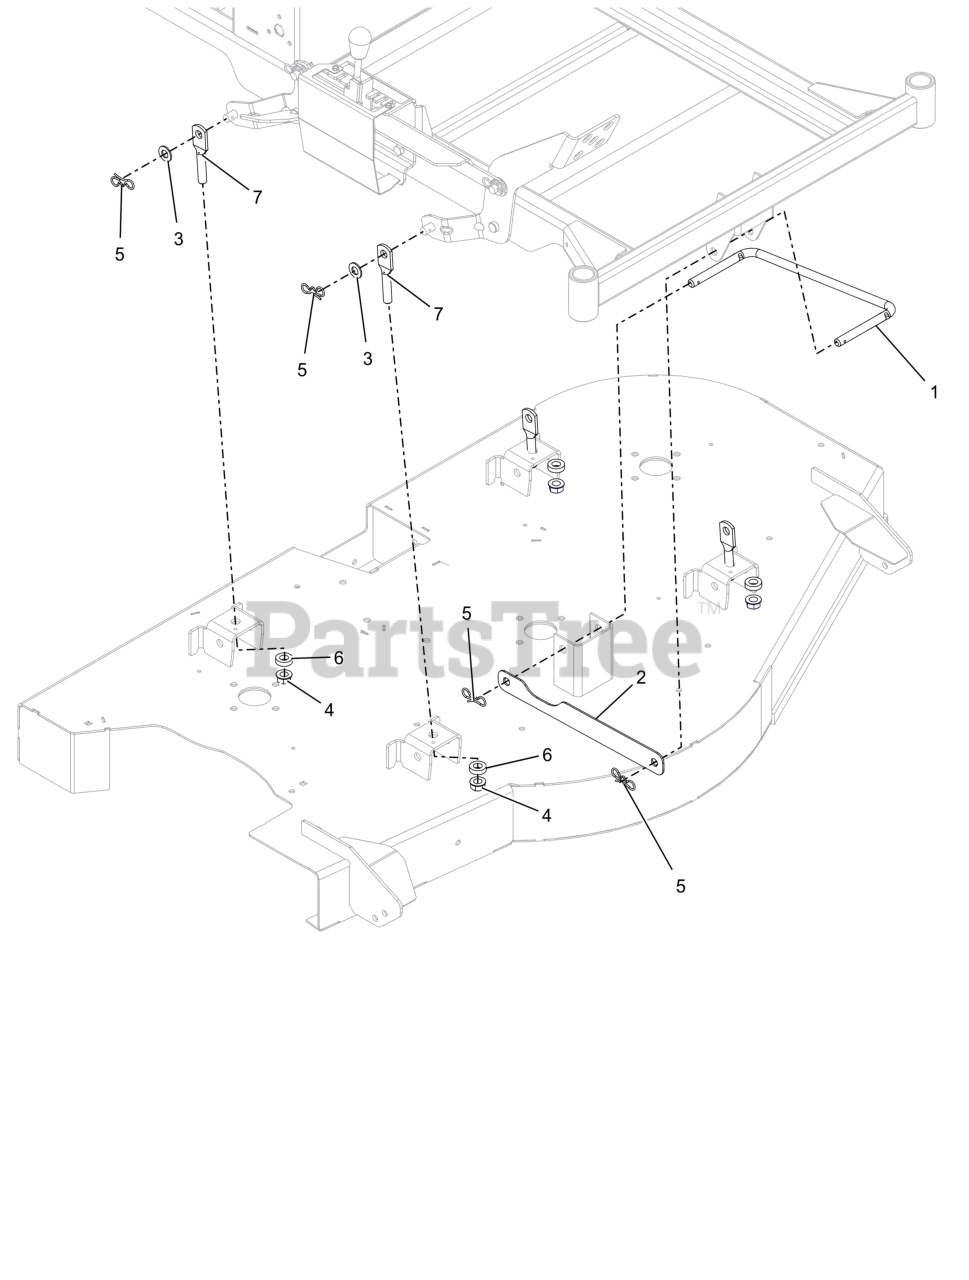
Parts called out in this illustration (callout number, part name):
1	WIREFORM, DRAG LINK
2	STRAP, DRAG LINK
3	WSHR-FL-NYL .518X1.000X.080
4	NUT-LK-CTR-FLG .500-13 GG ZCC
5	PIN, BOWTIE .091X1.875 ZCC
6	WASHER, RUBBER
7	LINK, DECK (HOLE-SHORT)
